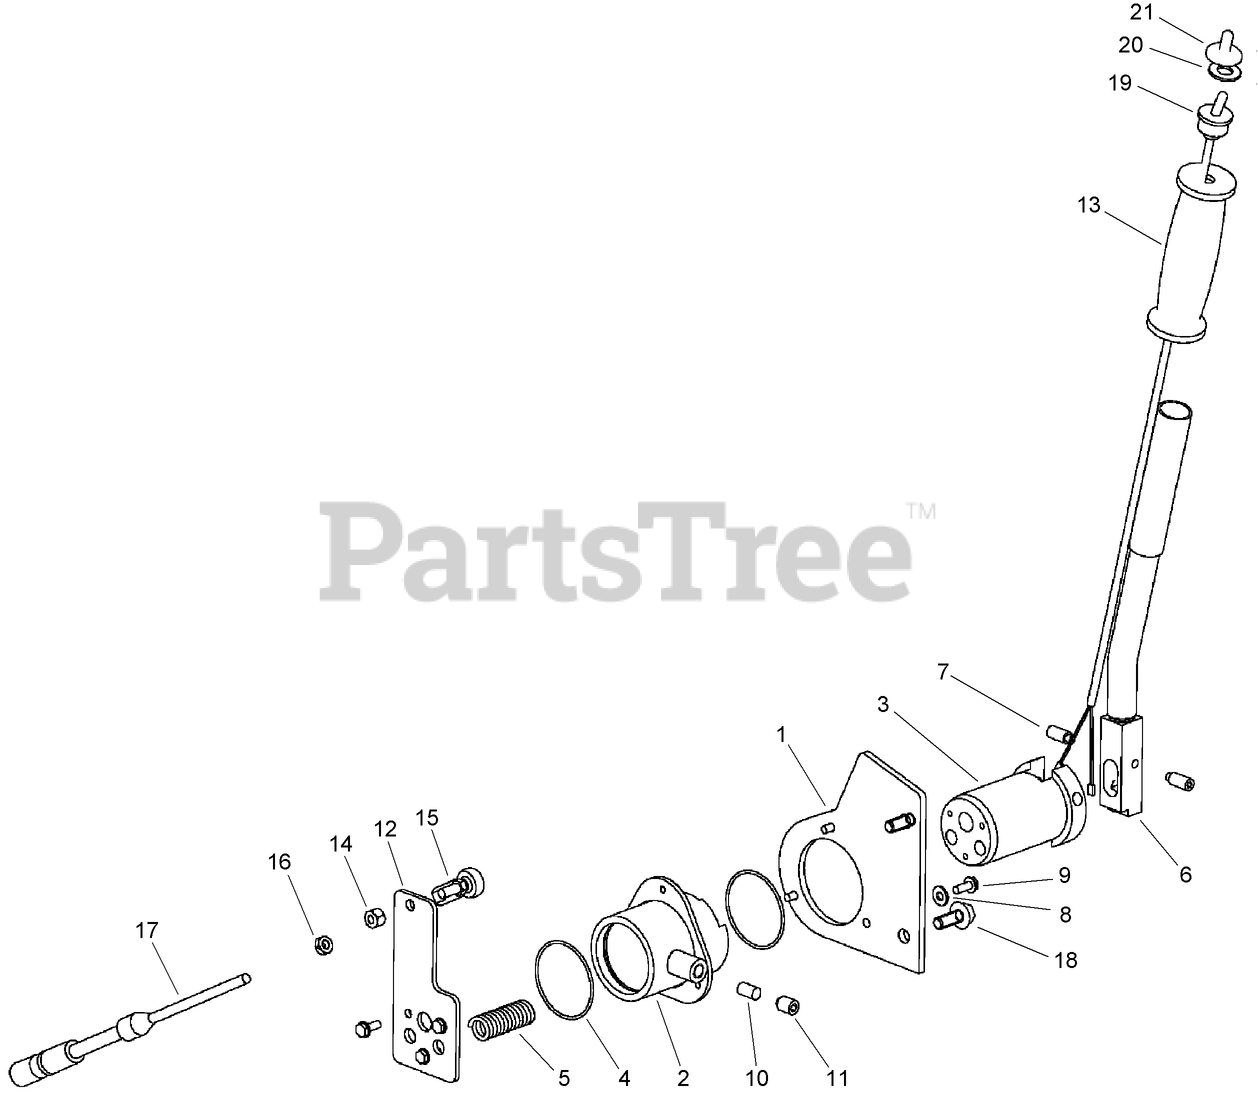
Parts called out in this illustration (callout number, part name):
1	PLATE-Gusset
4	O-RING
5	SPRING-Locking
6	HANDLE
7	SCREW-Set
8	WASHER-0.219 x 0.500 x 0.049 in CST ZND
9	SCREW-Hex Flange Hd
10	PLUG-FRICTION
11	SCREW-HSH
12	PLATE-Control
13	GRIP-Handle
14	NUT-Prev Trq 1/4 GRA CAD DIRECT
15	ROD END-FEMALE
16	NUT-Hex Jam 0.250-28 UNF GR5 ZND
17	GROUND DRIVE CONTROL CABLE ASM
18	SCREW, METRIC FLANGE w/BODY - M8 x 20
19	ON/OFF TOGGLE SWITCH ASM
20	WASHER-0.406 x 0.812 x 0.065 in CST ZND
21	BOOT-SWITCH, TOGGLE
